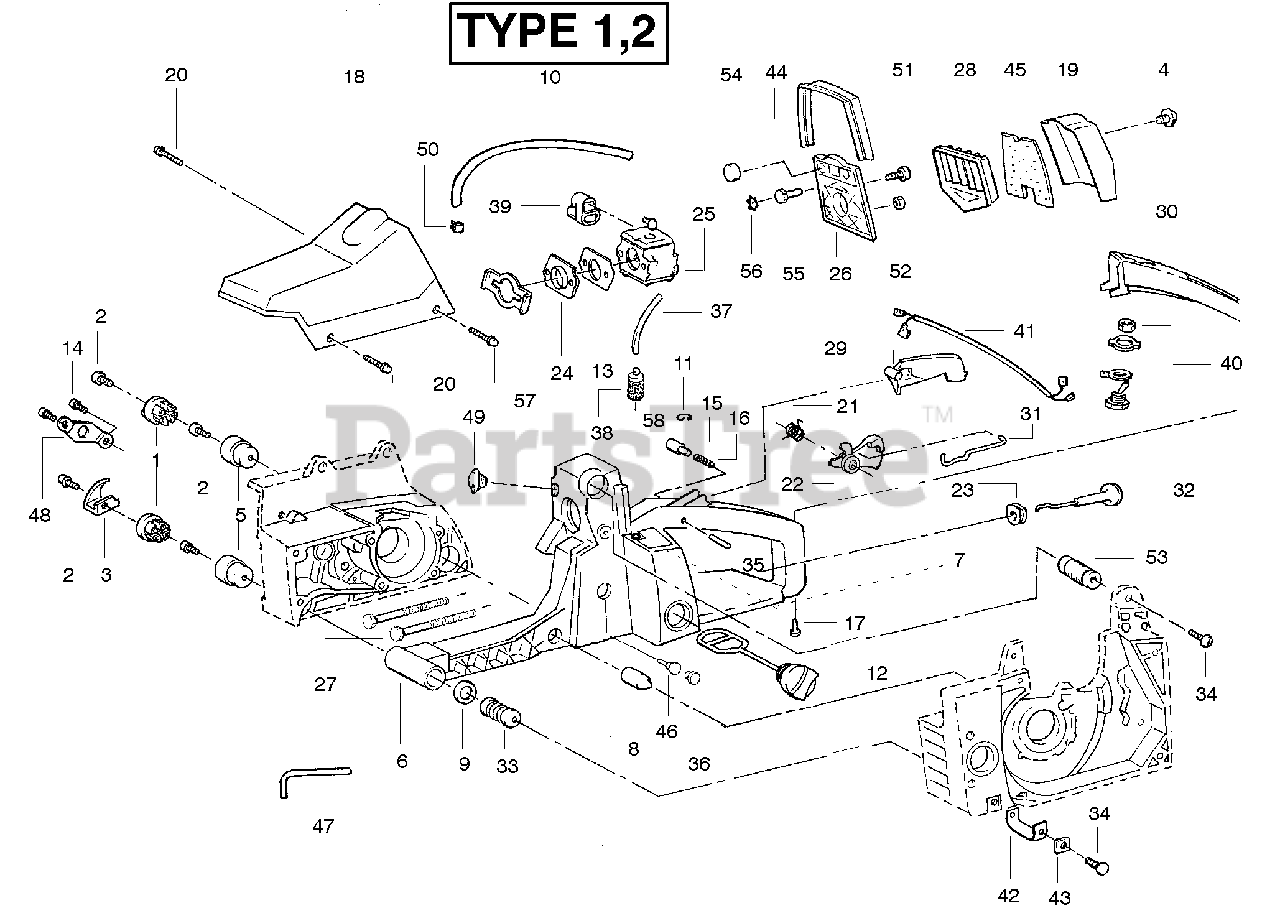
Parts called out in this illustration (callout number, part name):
1	Retainer-Chain Catcher
3	Chain Catcher
4	Knob-Carb. Cover
5	Lower Isolator
6	Rear Handle & Fuel Tank
7	Seal Carb. Cover-Left
8	Isolator Limiter
10	Impulse Line Kit
11	"C" Clip-Throttle Lock
12	Fuel Cap Ass’y.
13	Gasket - Carb.
15	Button Throttle Lock
16	Spring-Throttle
18	Cylinder Shield
19	Carb. Cover Ass’y.
21	Spring-Trigger Latch
22	Throttle Trigger
23	Grommet-Choke Rod
24	Bracket-Intake
25	Carburetor Kit w/limiter caps
26	Air Filter Base
27	Carb. Mounting Stud
29	Throttle Lockout
30	Rear Handle Cover
31	Throttle Wire
32	Rod & Wire Choke
34	Screw
35	Dowel Pin-Trigger
36	Plug-Bronze Vent
37	Fuel Line Kit
38	Fuel Pick-up Ass’y.
39	Grommet-Carburetor
41	Lead Wire Ass’y.
43	Strap Retainer Plate
47	Hex Wrench 5/32
48	Bracket-Retainer
51	Screw-Air Filter Base
53	Cylinder Mount Ass’y.
54	Bumper Carb Cover
55	Screw-Carb Knob
56	Retaining Ring
57	Bracket-Carb Stud
58	Seal Carb Cover-Right
